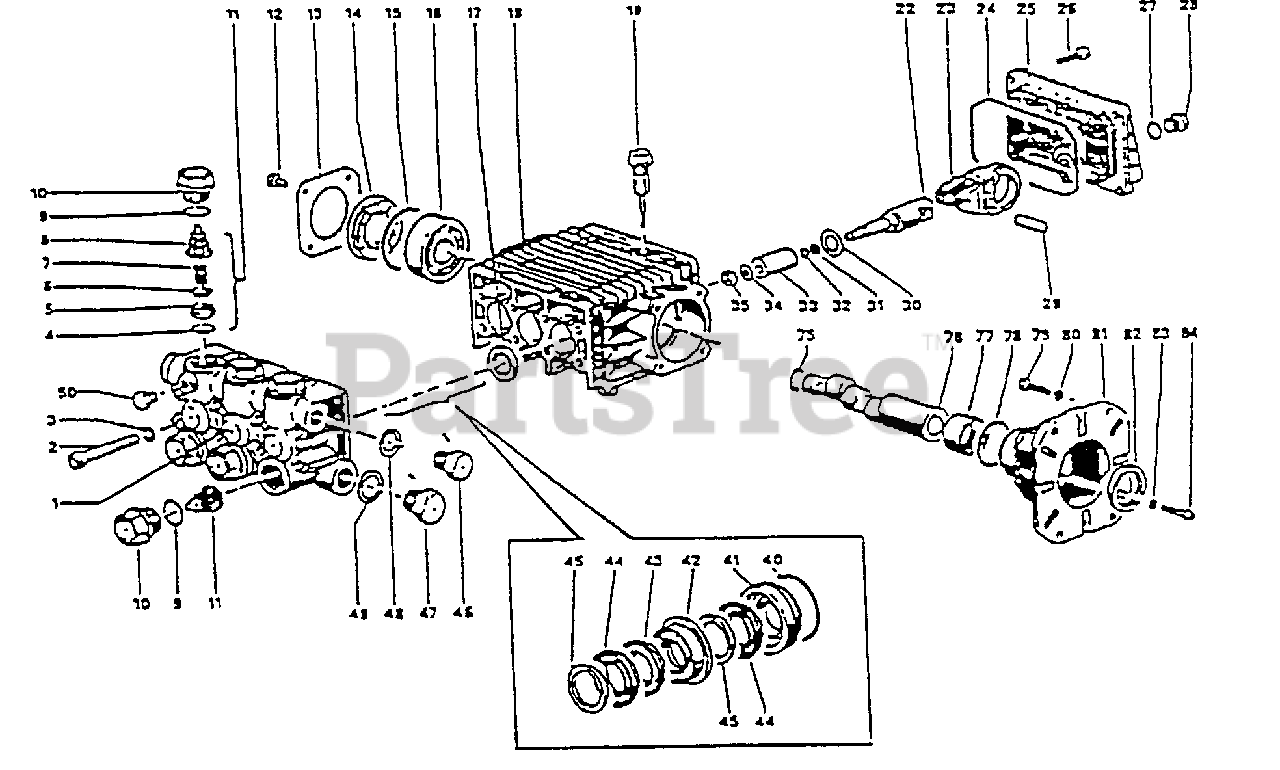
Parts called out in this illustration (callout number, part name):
1	Pump Head
5	Valve Seal
8	Valve Cage
11	Valve Assembly
13	Bearing Cover
16	Ball Bearing
18	Crankcase
19	Oil Dip Stick
22	Piston Guide
23	Connecting Rod
25	Rear Cover
28	Cap Screw
31	Anti-Ext. Ring
41	Packing Retainer
42	Intermed. Ring
45	Head Ring
46	Cap Screw
47	Cap Screw
50	Cap Screw
75	Retaining Ring
76	Crankshaft
77	Roller Bearing
79	Screw, 5/16 x 1
80	Washer, 3 mm
81	Gas Flange
